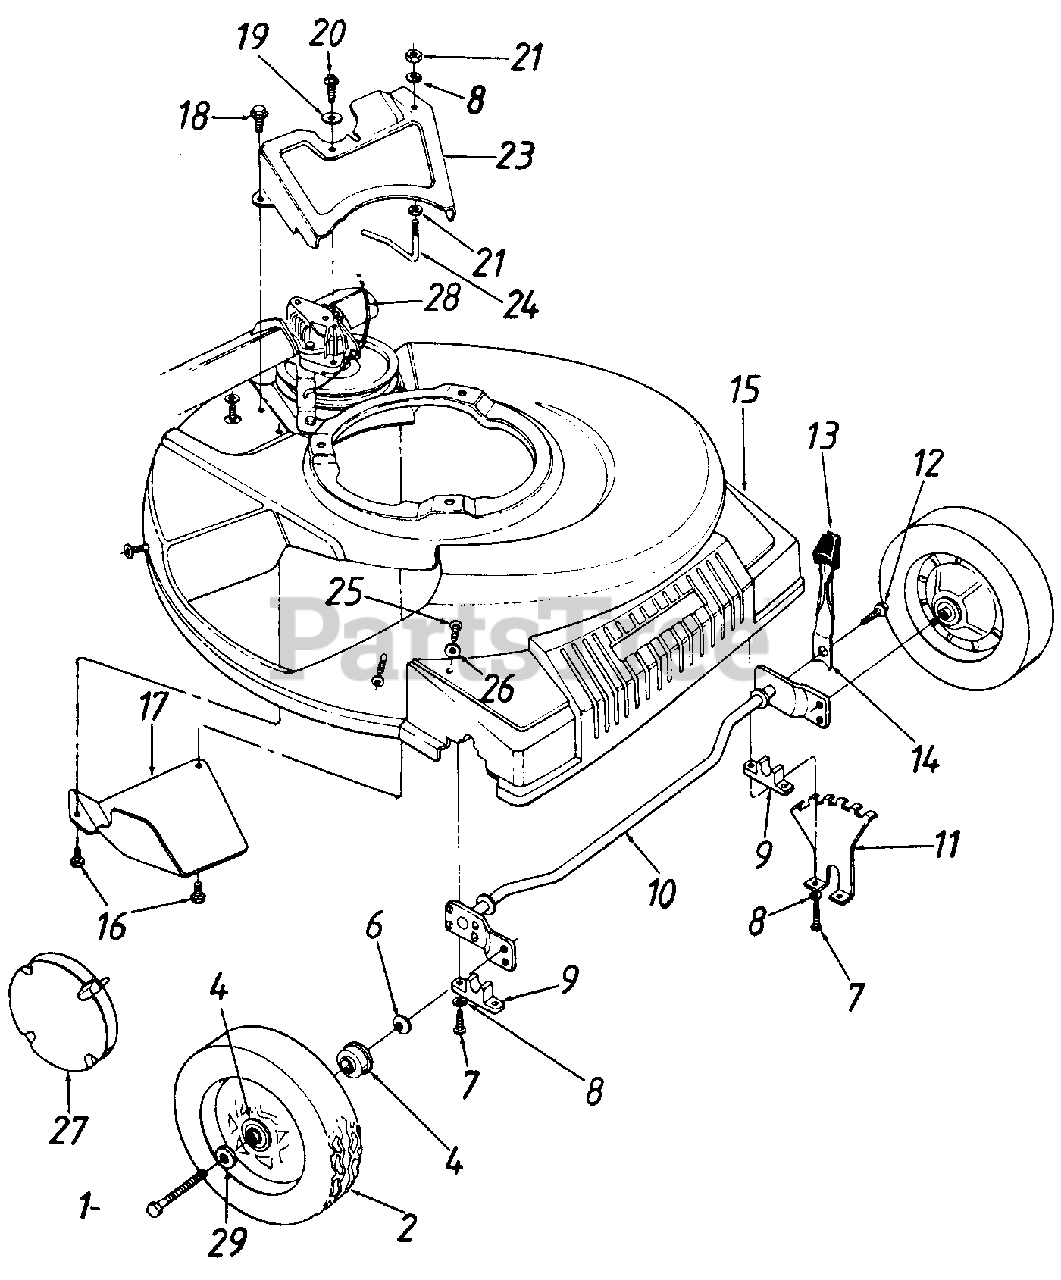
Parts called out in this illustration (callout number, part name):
1	Front Axle Bolt
2	Wheel Ass'y. Comp. 8 x 2"
4	Flange Ball Brg. .501 I.D.
6	Bell-Wash. .345" I.D. x .88
7	Hex Wash. Hd. B-Tap Scr. 1/4-20
8	L-Wash. 1/4" I.D.
9	Block Bushing
10	Axle Ass'y.
11	Height Adj. Bracket
12	Hex Wash. Hd. TT-Tap Scr. 1/4-20 x .5" Lg.
13	Knob
14	Spring Lever
15	Plastic Front End
16	Hex B-Tap Scr. 1/4-.38"
19	Bell-Wash. .265" I.D. x .75
20	Hex Wash. Hd. B-Tap Scr. 1/4 X .6211
21	Hex Nut 1/4-20 Thd.
23	Transmission Belt Guard
24	S.P. Belt Guard
25	Truss B-Tap Scr. 5/16 x .75" Lg.
26	Bell-Wash. 5/16" I.D. x 5/8"
27	Hub Cap
28	S.P. Cable 50" Lg.
29	Fl-Wash. .531" I.D.
